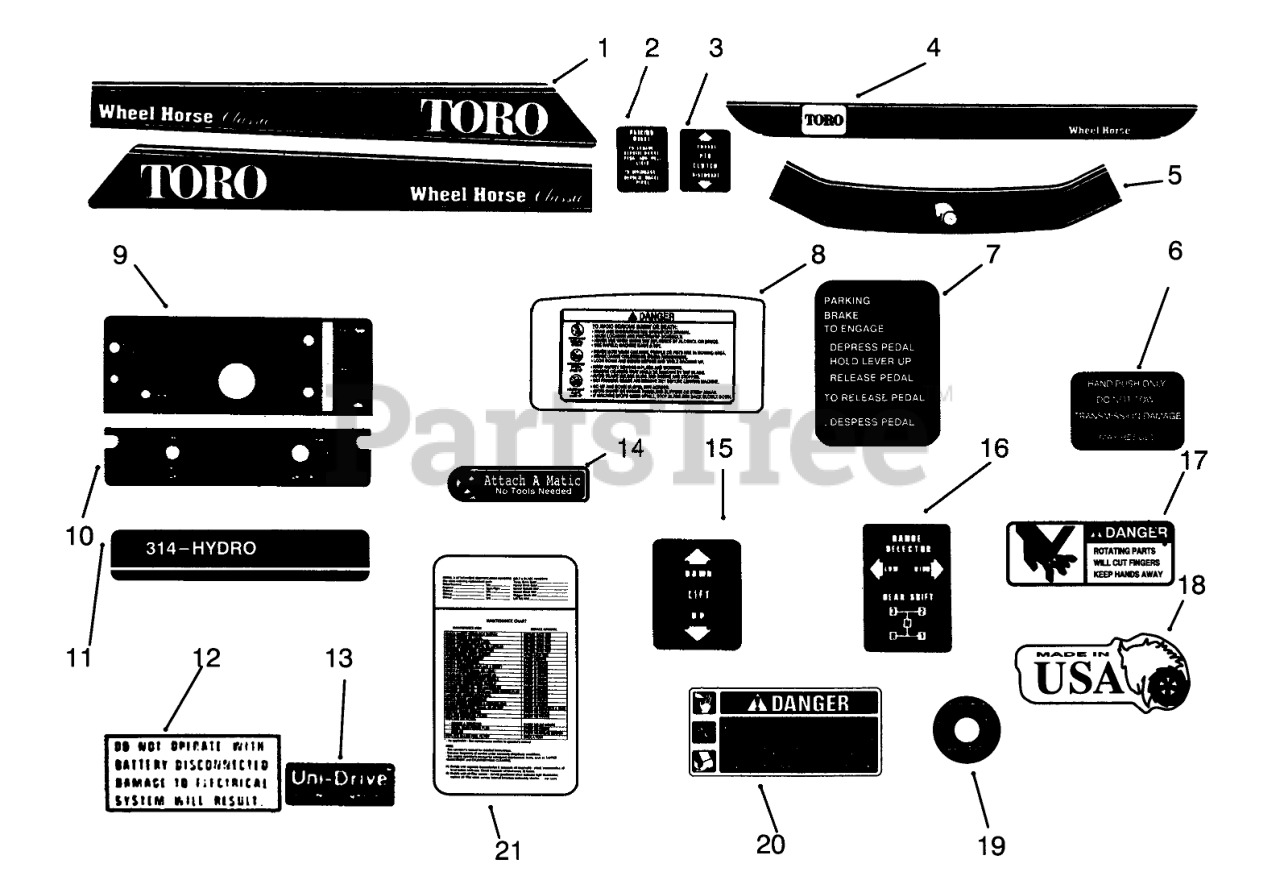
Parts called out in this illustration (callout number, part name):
1	DECAL-HOOD CLASSIC
2	DECAL-PARKING, BRAKE
3	DECAL PTO CLUTCH
4	DECAL-FENDER
5	DECAL-FRONT HOOD
6	DECAL-DO NOT TOW
7	DECAL-PARKING BRAKE
8	Decal-Danger
9	DECAL-LOWER DASH
10	Decal-Switch Plate
11	DECAL-312 HYDRO
12	DECAL ELECT SYSTEM
13	Decal-Unidrive
14	Decal-Attac-O-Matic
15	DECAL-LIFT
16	DECAL-SHIFT PATTERN
17	DECAL - DANGER
18	Decal-Made In USA
19	Decal-Air Cleaner
20	DECAL-DANGER
21	Decal-Maintenance
